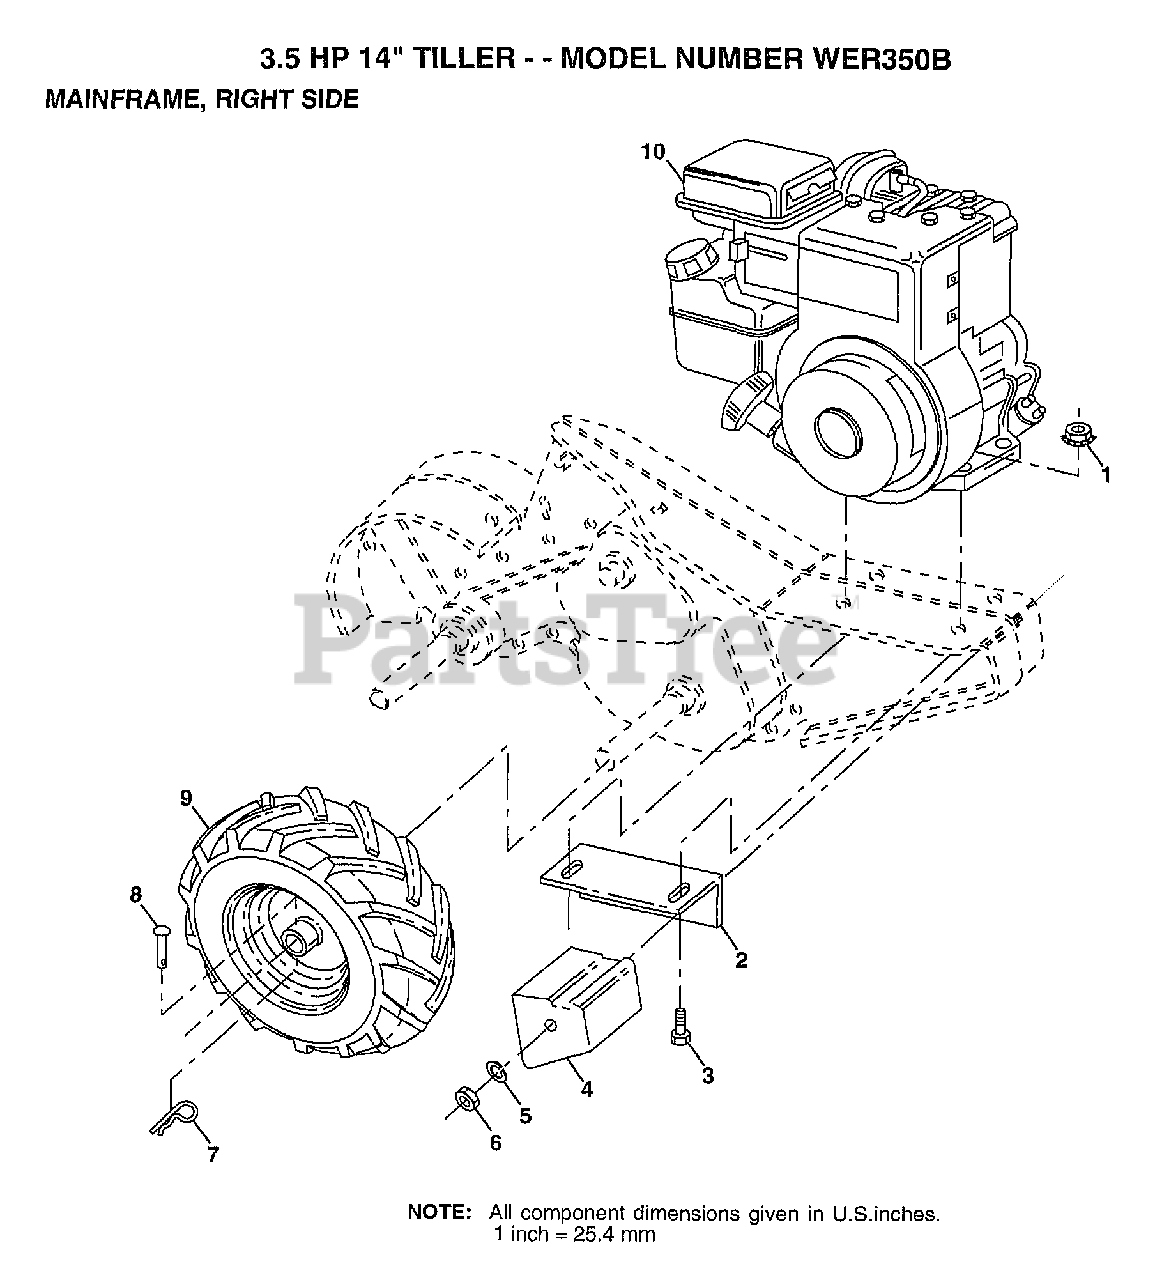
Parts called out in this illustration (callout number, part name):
2	BRACKET RH CRT
3	BOLT.HEX.5/16-1.5
4	COUNTERWEIGHT CRT
5	LOCKWASHER
6	NUT.HEX.3/8-16UNC
7	RETAINER M
8	RIVET.DRILL.1.75
9	TIRE.CHV.13X5.0-6
9	RIM
